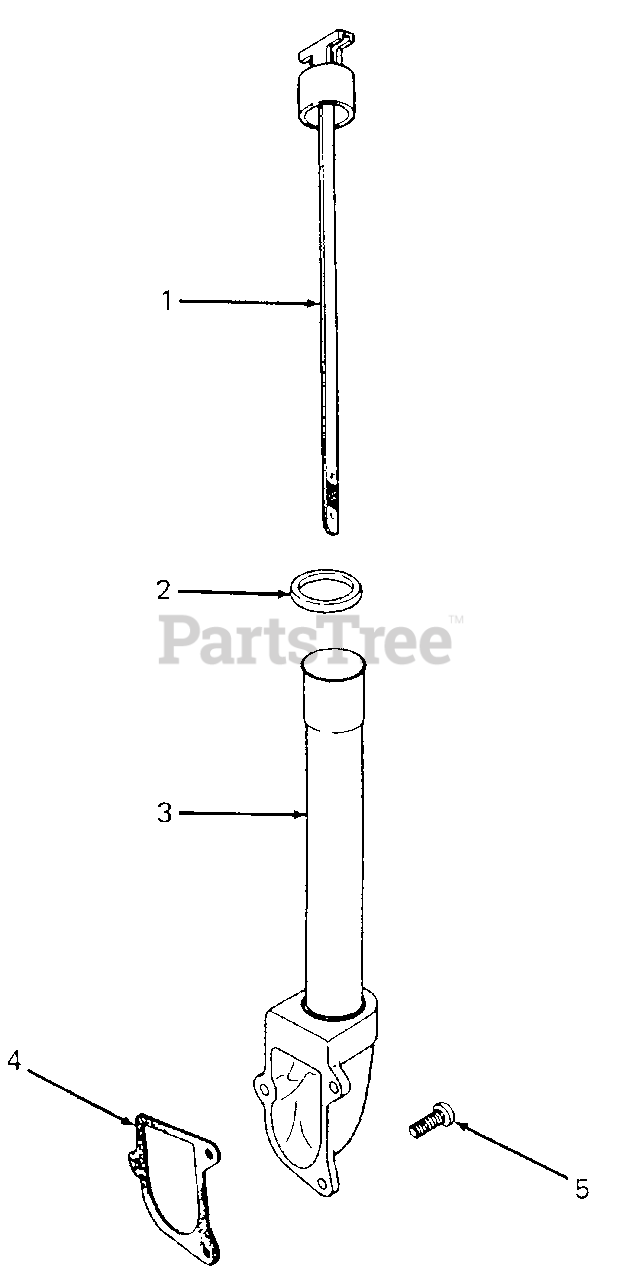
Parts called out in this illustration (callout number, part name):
1	Dipstick, 13-1/8"
3	Adapter, Oil Fill
5	Screw, RH Sems, 10-24 X 1/2
